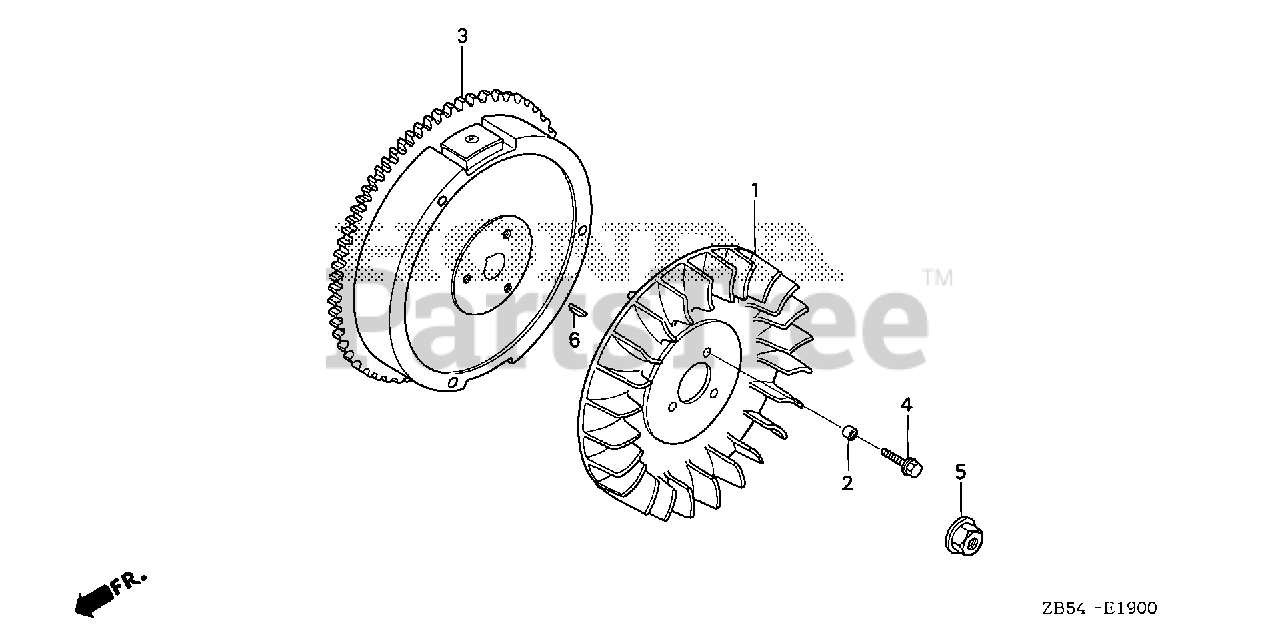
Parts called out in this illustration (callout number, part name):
1	FAN, COOLING
2	COLLAR, FAN
4	BOLT, FLANGE (6X16)
5	NUT, SPECIAL (16MM) (1)
6	KEY, SPECIAL WOODRUFF (25X18)
